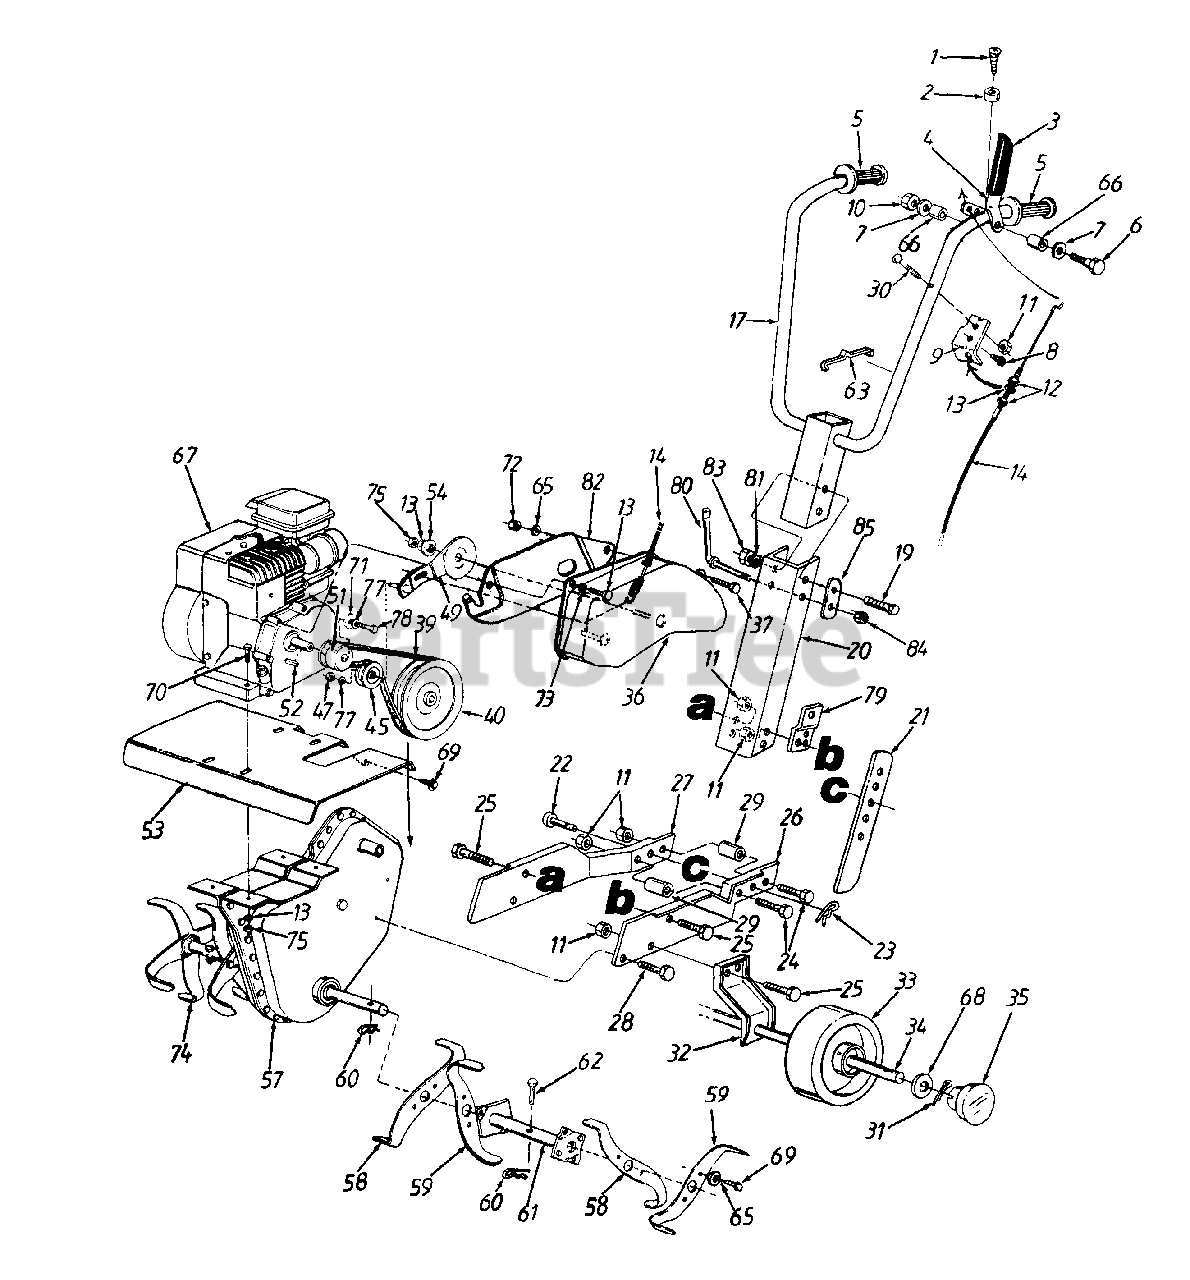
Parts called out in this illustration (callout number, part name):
1	Tap Scr. #10-16 x 1/2" Lg.
2	Rubber Bumper
5	Handle Grip
6	Hex Bolt 1/4-20 x 2" Lg.
7	Fl-Wash. 1/4" I.D.
8	Hex Tap Scr. 1/4-20 x 1/2" Lg.
9	Cable Bracket
10	Lock Nut 1/4-20 Thd.
11	Lock Nut 5/16-18 Thd.
12	Hex Jam Nut 5/16-24 Thd.
13	L-Wash. 5/16" I.D.
14	Clutch Control Cable
23	Hairpin Cotter
24	Hex Bolt 5/16-18 x 1" Lg.
25	Hex Bolt 5/16-18 x 5/8" Lg.
29	Spacer
30	Hex Bolt 5/16-18 x 1-1/4" Lg.
31	Cotter Pin
34	Axle - Wheel
39	V-Belt
40	Pulley - Chain Case
45	Flat Idler Pulley
47	Hex Jam L-Nut 3/8-24 Thd.
49	Idler Arm Ass'y.
51	Engine Pulley
52	Square Key 3/16" x .75" Lg.
57	Chain Case Ass'y. Comp.
63	Cable Tie - Plastic
65	L-Wash. 1/4" I.D.
67	Engine
68	Fl-Wash. 3/8" I.D.
69	Tap Scr. 1/4-20 x 1/2" Lg.
70	Hex Bolt 5/16-18 x 1-1/2" Lg.
71	Fl-Wash. 3/8" I.D. x 1" O.D.
72	Hex Nut 1/4-20 Thd.
73	Hex Bolt 5/16-24 x .5" Lg.
77	L-Wash. 3/8" I.D.
78	Hex Bolt 3/8-24 x 1" Lg.
81	Fl-Wash. .385" I.D. x .87" O.D.
84	Hex Flange L-Nut 3/8-24 Thd.
85	Retainer Bracket
